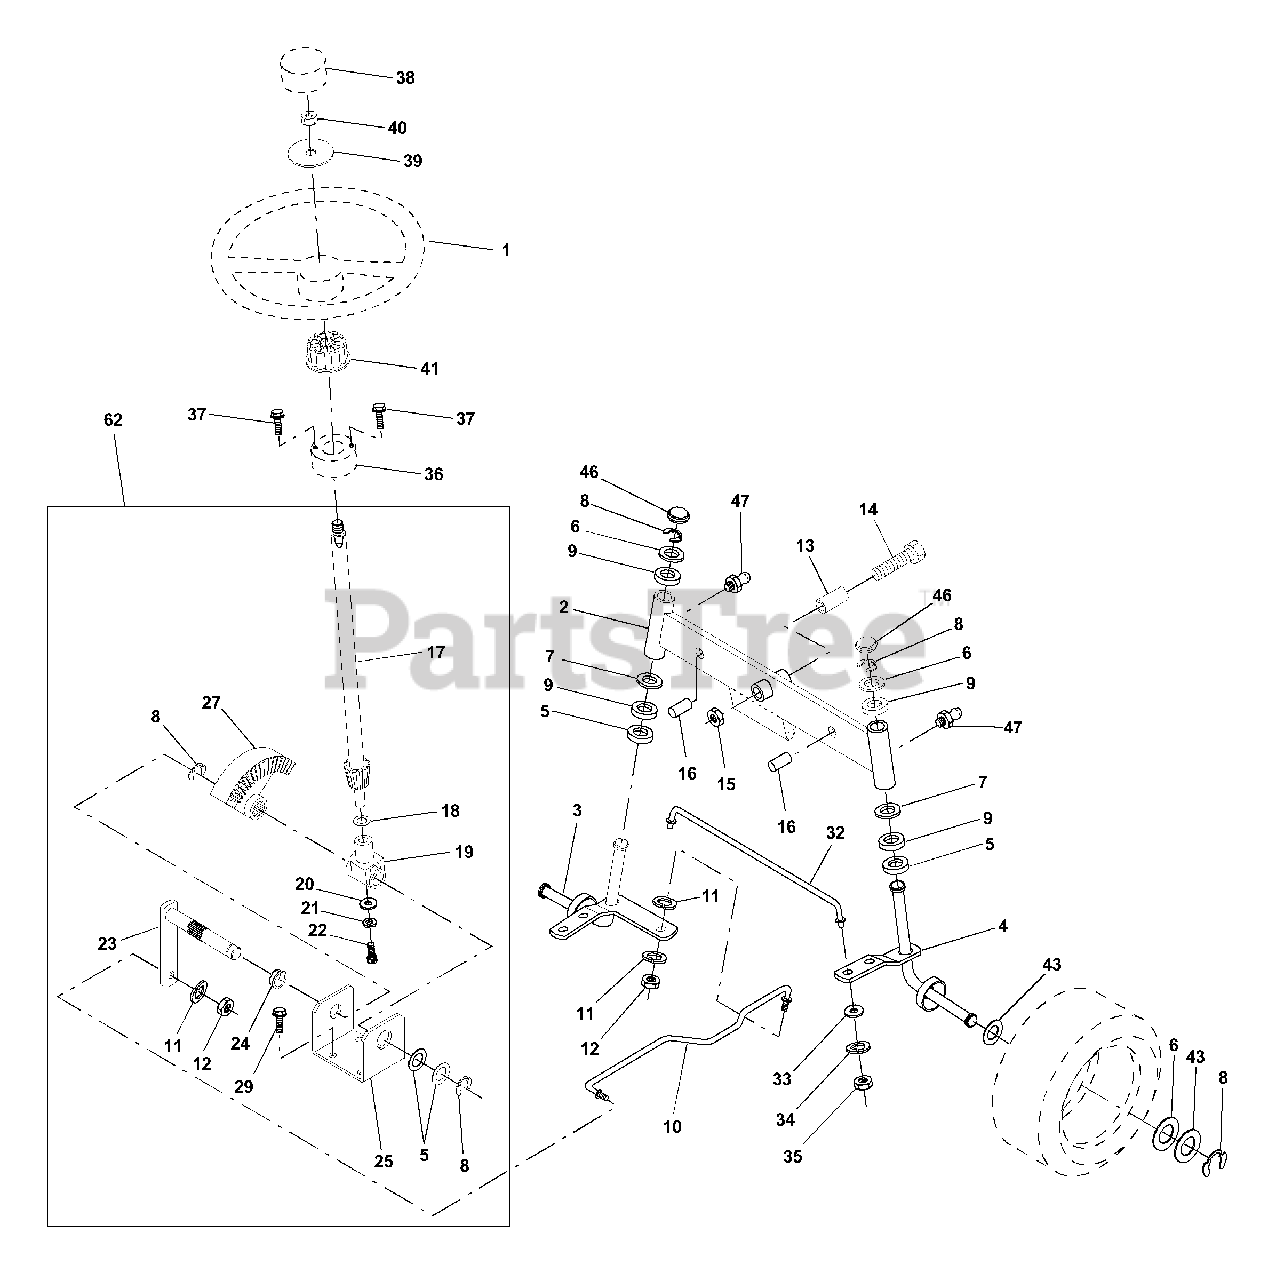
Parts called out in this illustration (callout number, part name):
1	Wheel Steering Auto Grey
2	Axle Asm Fr LT W/gzks 38/42
3	Spindle Asm LH
4	Spindle Asm RH
5	Bearing Race Thrust Harden
6	Washer 25/32 X 1-5/8 X 16 Ga
7	Washer 27/32 X 1-1/4 X 16 Ga
8	Ring Klip #t5304-75
9	Bearing Col Strg Blk
10	Link Drag Sol Ball Jt 20 064
11	Washer Lock Hvy Hlcl Spr 3/8
12	Nut Fin Hex 3/8-24 Unf
13	Spacer Bearing Axle Front
14	Bolt Hex 5/8-11 Unc X 3-1/2
15	Nut Lock Flange 5/8-11 Unc
16	Pin Axle 5/8 X 1 55/1 54 Lg
17	Shaft Asm Strg 20 31 x 3/4 YP YT
18	Washer Thrust 515x 750x 033
19	Support Shaft
20	Washer Shim 1/4 X 5/8 X 062
21	Washer Lock Hvy Helical 1/4
22	Screw Hex Socket 1/4-20 X 5/8
23	Shaft Asm Pittman
24	Nyliner Snap In
25	Bracket Steering
27	Gear Sector
29	Screw Thdrol 3/8-16x3/4 Ty-tt
32	Rod Tie Wire Form 19 75 Elec
33	Washer 11/32 x 3/4 x 16 Ga.
34	Washer, Lock Hvy Hlcl Spr 5/16
35	Locknut 5/16-24 Unf
36	Bushing Strg Angle 3/4"
37	Screw Slftp #10-16 X 1/2 Ty-b
38	Insert Cap Strg Wh Aut Hus Gry
39	Washer 53 X 2 25 X 160 Zinc
40	Nut Hex Jam Toplock 1/2-20 Unf
41	Adapter Wheel Strg 758/ 753id
43	Washer 25/32 X 1 1/4 X 16 Ga
46	Cap Spindle Fr Top Blk
47	Fitting Grease
